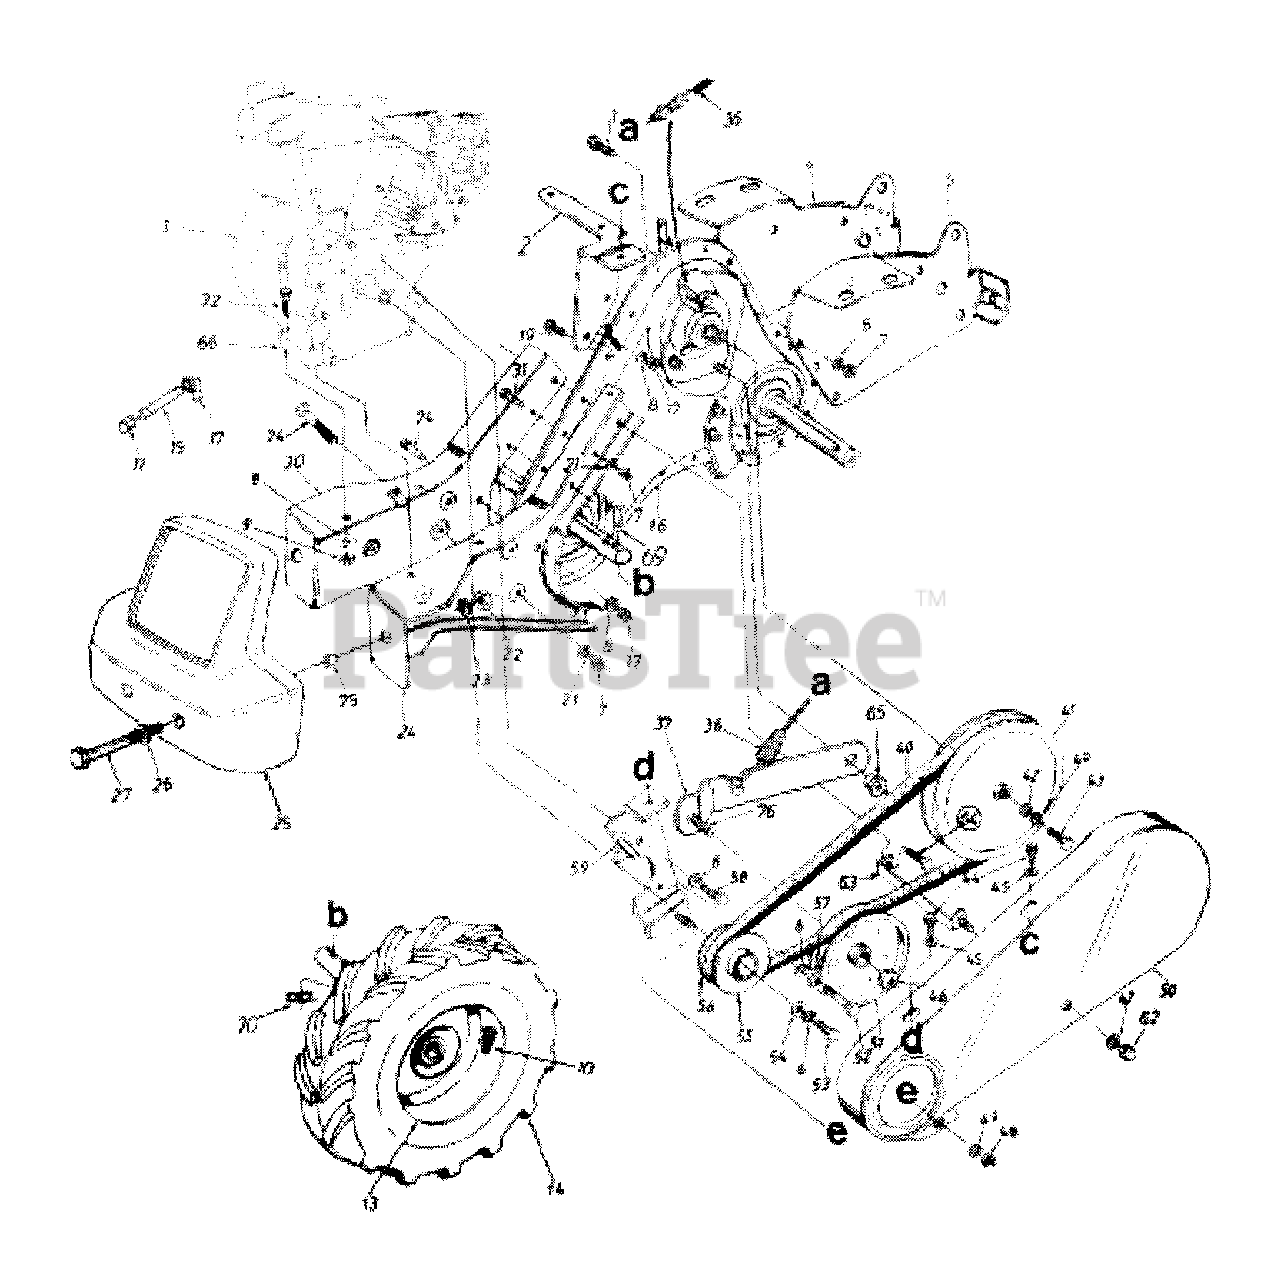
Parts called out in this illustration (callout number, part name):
1	Engine
7	Hex Nut 3/8-16 Thd
8	L-Wash. 5/16" I.D.
9	Hex Nut 5/16-18" Thd."
10	Air Valve
11	Cap:End:1/4 Npt.
15	Pipe:Straight:1/4 Npt x 3.5" Lg.
16	Gear Case Ass'y. Comp.
17	Elbow Street 1/4 Npt.
19	Hex Bolt 5/16-18 x 1" Lg.
22	Hex Nut 1/2-20
23	L-Wash. 1/2" I.D.
26	Fl-Wash. .510" I.D. x 1.0"
27	Hex Bolt 1/2-20 x 5.5" Lg.
32	Hex Bolt 5/16-18 x 2.75"
36	Clutch Control Cable 46" Lg.
37	Idler Bracket
40	"V"-Belt
41	Fl-Pulley 8" O.D.
42	Fl-Wash. 1/4" I.D. x .93" O.D.
43	Hex Bolt 1/4-28 x .75" Lg.
44	Hex Wash. Hd. 8-Tap Scr 1/4-20 x .50" Lg.
45	Fl-Wash. .281" I.D. x .625"
46	Jam Cnter L-Nut 3/8-16 Thd.
47	Fl-Wash. .266" I.D. x .625" O.D.
48	Hex Nut 1/4-20 Thd.
49	L-Wash. 1/4" I.D.
50	Belt Cover
51	Fl-Idler w/Flanges 3.75" O.D.
52	Hex Bolt 5/16-24 x 1.75"
53	Hex Bolt 3/8-24 x 1.00" Lg.
55	Outer Engine Pulley Half
56	Inner Engine Pulley Half
57	Hex Nut 5/16-24 Thd.
58	Hex Bolt 5/16-24 x .62" Lg.
59	Belt Keeper Ass'y.
62	Hex Cap Nut 1/4-28 Thd.
63	Belt Cover Brkt. Ass'y.
64	Hex Bolt 5/16-18 x 1" Lg. (Gr. 5)
65	Shld. Nut
66	Engine Spacer Block
69	Clevis Pin
70	Hairpin Clip
74	Screw 5/16-18 x 1"
76	Hex Cap Scr. 2/8-16: 1.25 Lg.
